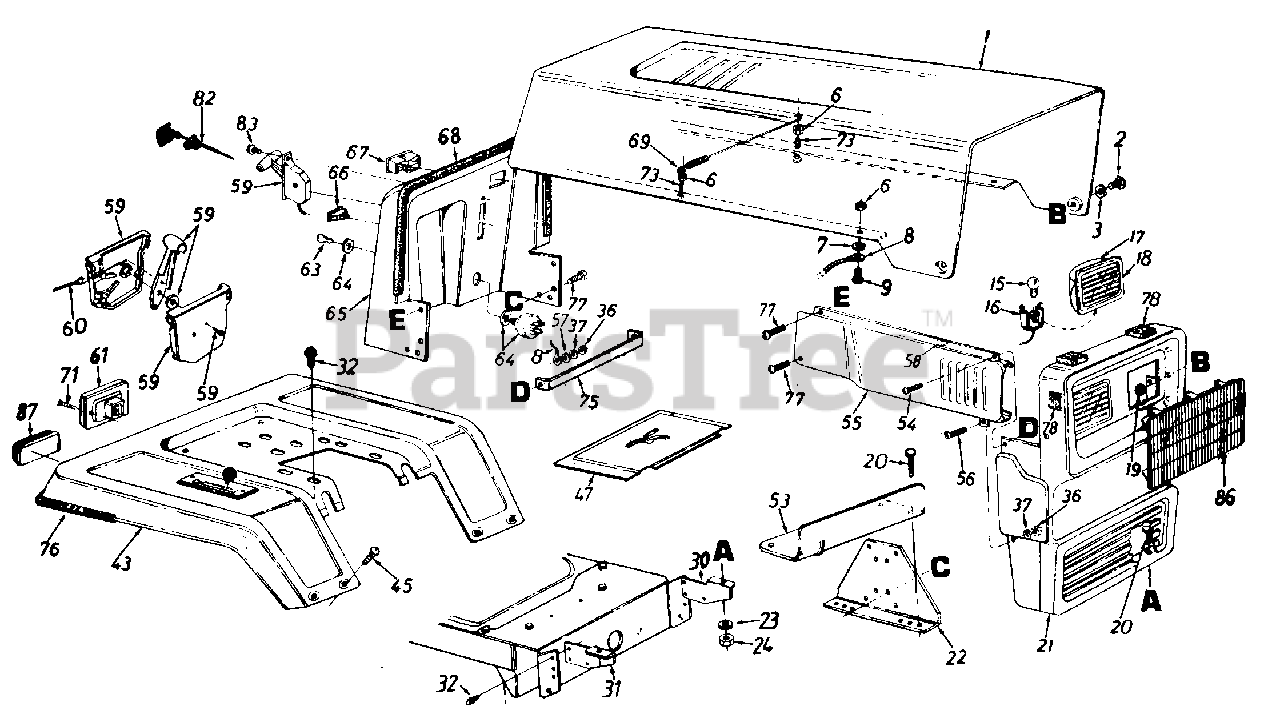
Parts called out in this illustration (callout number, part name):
3	Washer .39" I.D. x .62"
6	Hex Sems Nut #10-24 Thd.
7	Fl-Wash. .203" I.D. x .41"
8	Hood Stop
9	Truss Hd. Scr. #10-24 x 1/2"
15	Lamp
16	Twist Lock-Lamp Socket
17	Headlight Housing
18	Lens
19	L-Nut 1/4-28 Thd.
20	Hex Bolt 5/16-18 x .75" Lg.
23	L-Wash. 5/16" I.D.
24	Hex Nut 5/16-18 Thd.
30	Grille Mount Brk't.-L.H.
36	Hex Nut 1/4-20 Thd.
37	L-Wash. 1/4" I.D.
47	Transmission Panel
53	Fuel Tank Support
54	Truss Hd. Scr. 1/4-20 x .75"
55	Side Cover-R.H.
57	Fl-Wash. .281" I.D. x .73" O.D.
58	Mounting Clamp
59	Throttle Control Box Ass'y.
60	Throttle Control Wire
61	Taillight
63	Ignition Key
64	Ignition Switch
67	Ammeter
68	Trim Strip-27"
69	Hood Spring
71	Truss Hd. AB-Tap Scr. #6 x .62" Lg.
73	Hex Scr. #10-24 x 1.0" Lg.
75	Tie Strap-Grille/Side Panel
76	Trim Strip-81"
77	Hex Wash. Hd. Tap Scr. 1/4 x .75" Lg.
82	Choke Control 29" Lg.
83	Truss Mach. AB-Tap Scr. #10 x .5" Lg.
86	Headlight Bezel
87	Reflector
